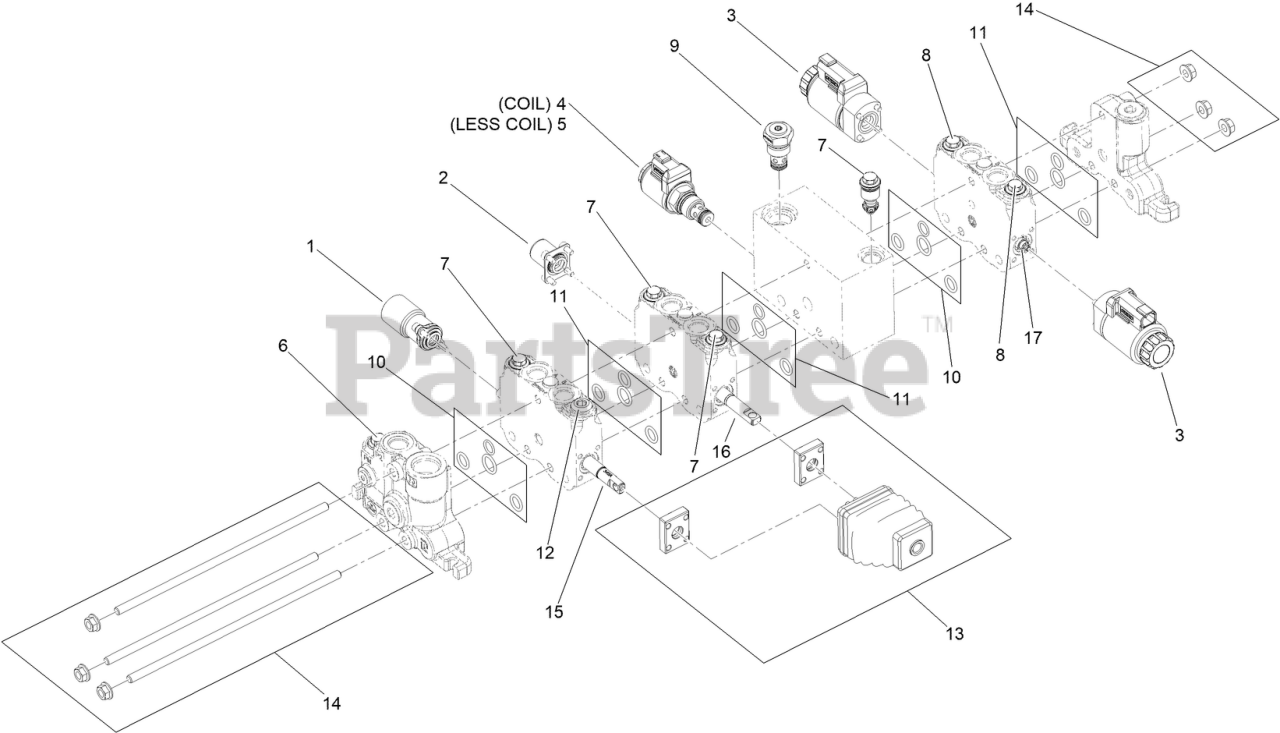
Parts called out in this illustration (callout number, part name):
1	SPOOL CONTROL
2	SPOOL CONTROL
3	SPOOL CONTROL
4	VALVE-SOLENOID
5	VALVE-SOLENOID
6	VALVE-RELIEF, MAIN
7	VALVE-RELIEF
8	VALVE-RELIEF
9	VALVE-CHECK
10	KIT-SEAL
11	KIT-SEAL
12	PLUG-CAVITY
13	KIT-JOYSTICK
14	KIT-TIE ROD
15	SPOOL-VALVE
16	SPOOL-VALVE
17	SPOOL-VALVE
